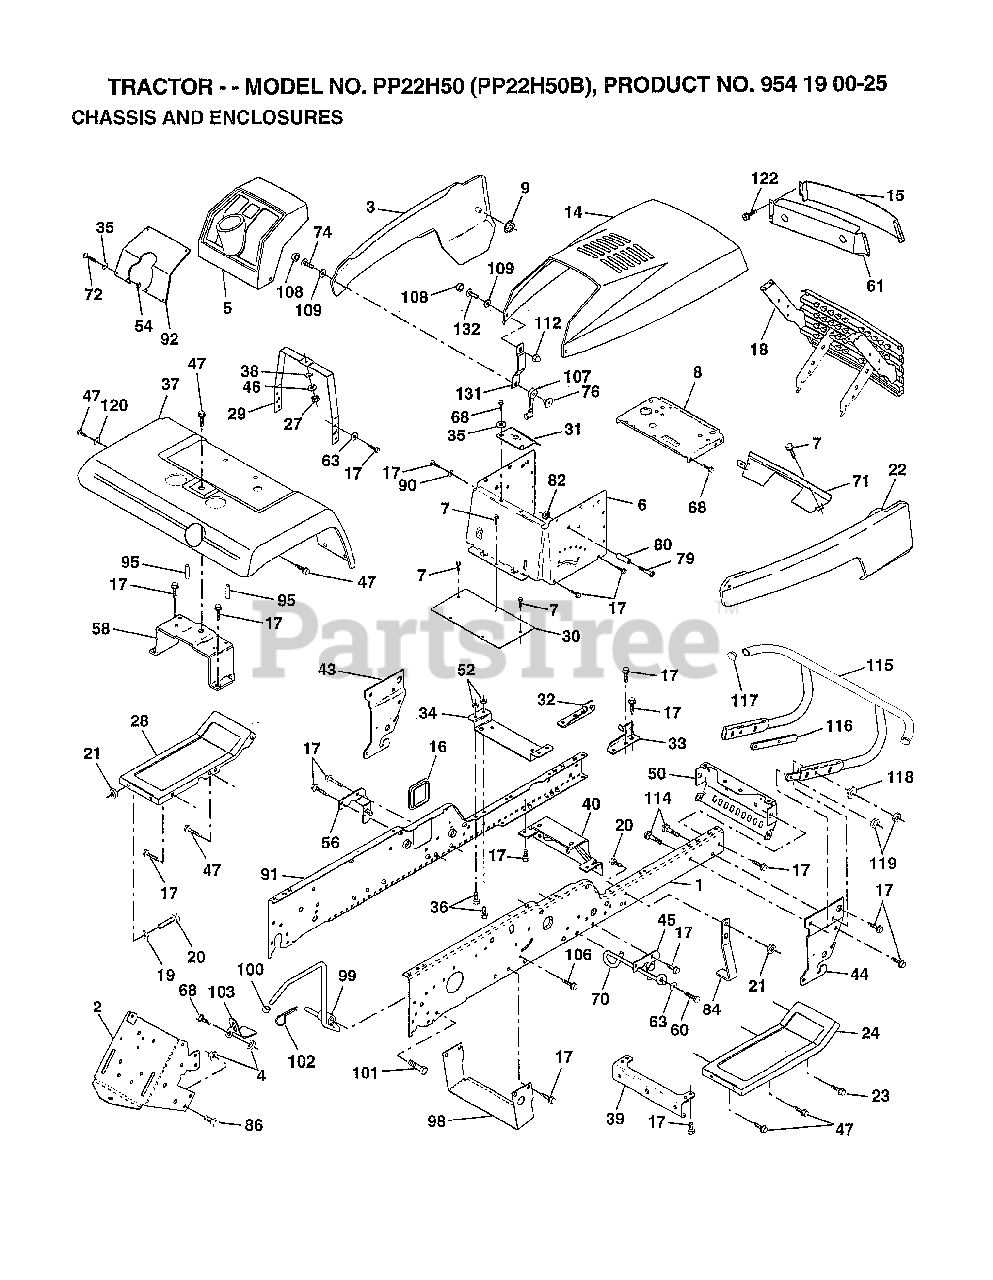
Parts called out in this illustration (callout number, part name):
1	"RAIL,FRAME RH"
2	DRAWBAR GT
3	"PANEL ASM-SIDE,LH"
4	NUT.7/16
5	DASHBOARD BLACK
6	DASH LOWER
7	SCREW
8	SUPPORT.DASH.BTRY
9	PAL NUT LT
14	"HOOD, YARD PRO"
15	LENS.BAR.CLEAR
16	COVER ACCESS
17	SCREW
19	WASHER
20	BOLT
22	"PANEL ASM SIDE,RH"
23	SCREW GTV
24	FOOTREST.RH.LT/GT
28	FOOTREST.LH.LT/GT
29	DASH.SUPT.YP/HUSQ
30	SADDLE.HYDRO.95
31	BRKT SUPT 1-PC VG
32	BRACKET ASM FRAME
33	BRACKET ASM FRAME
34	BRACKET.ENG.SUPT.
35	WASHER
36	BOLT
37	FENDER.PNT.
38	LOCKWASHER
39	BRACKET.AXLE.FRT.
40	"BRKT SUPPORT,AXLE"
43	BRACKET.SUS.FT.LH
44	BRACKET.SUS.FT.RH
45	BRACKET.SUSP.RH.
46	WASHER PM
47	SCREW LT
50	"BRKT CHASSIS,FRNT"
56	BRACKET.SUSP.LH.
58	BRKT.ASM.FENDER
60	SCREW
61	BEZEL.ASM.
63	WASHER
70	GUIDE.BELT.MID.SP
72	SCREW
74	SCREW
76	WELDNUT
79	SCREW
80	SPACER LT
84	STOP.OVER.CENTER
86	BOLT
90	LOCKWASHER
91	"RAIL FRAME,LH"
92	PLATE, SILKSCREEN DASH
95	NUT-PUSH YT
98	BRACKET SKID CHAS
99	ROD BYPASS
101	SCREW LT
103	LOCK BYPASS BRKT
107	HOOD LATCH T
108	SNAP CAP LT
109	WASHER LT
112	ACORN NUT RB
114	BOLT.3/8-14X1.25
115	BUMPER.ASM
116	BRACKET.EXT.BUMP.
117	PLUG.PLASTIC
118	WASHER
120	WASHER HYT
122	SCREW.HEX.WS.HD
131	BKT.SPT.HOOD/PANL
